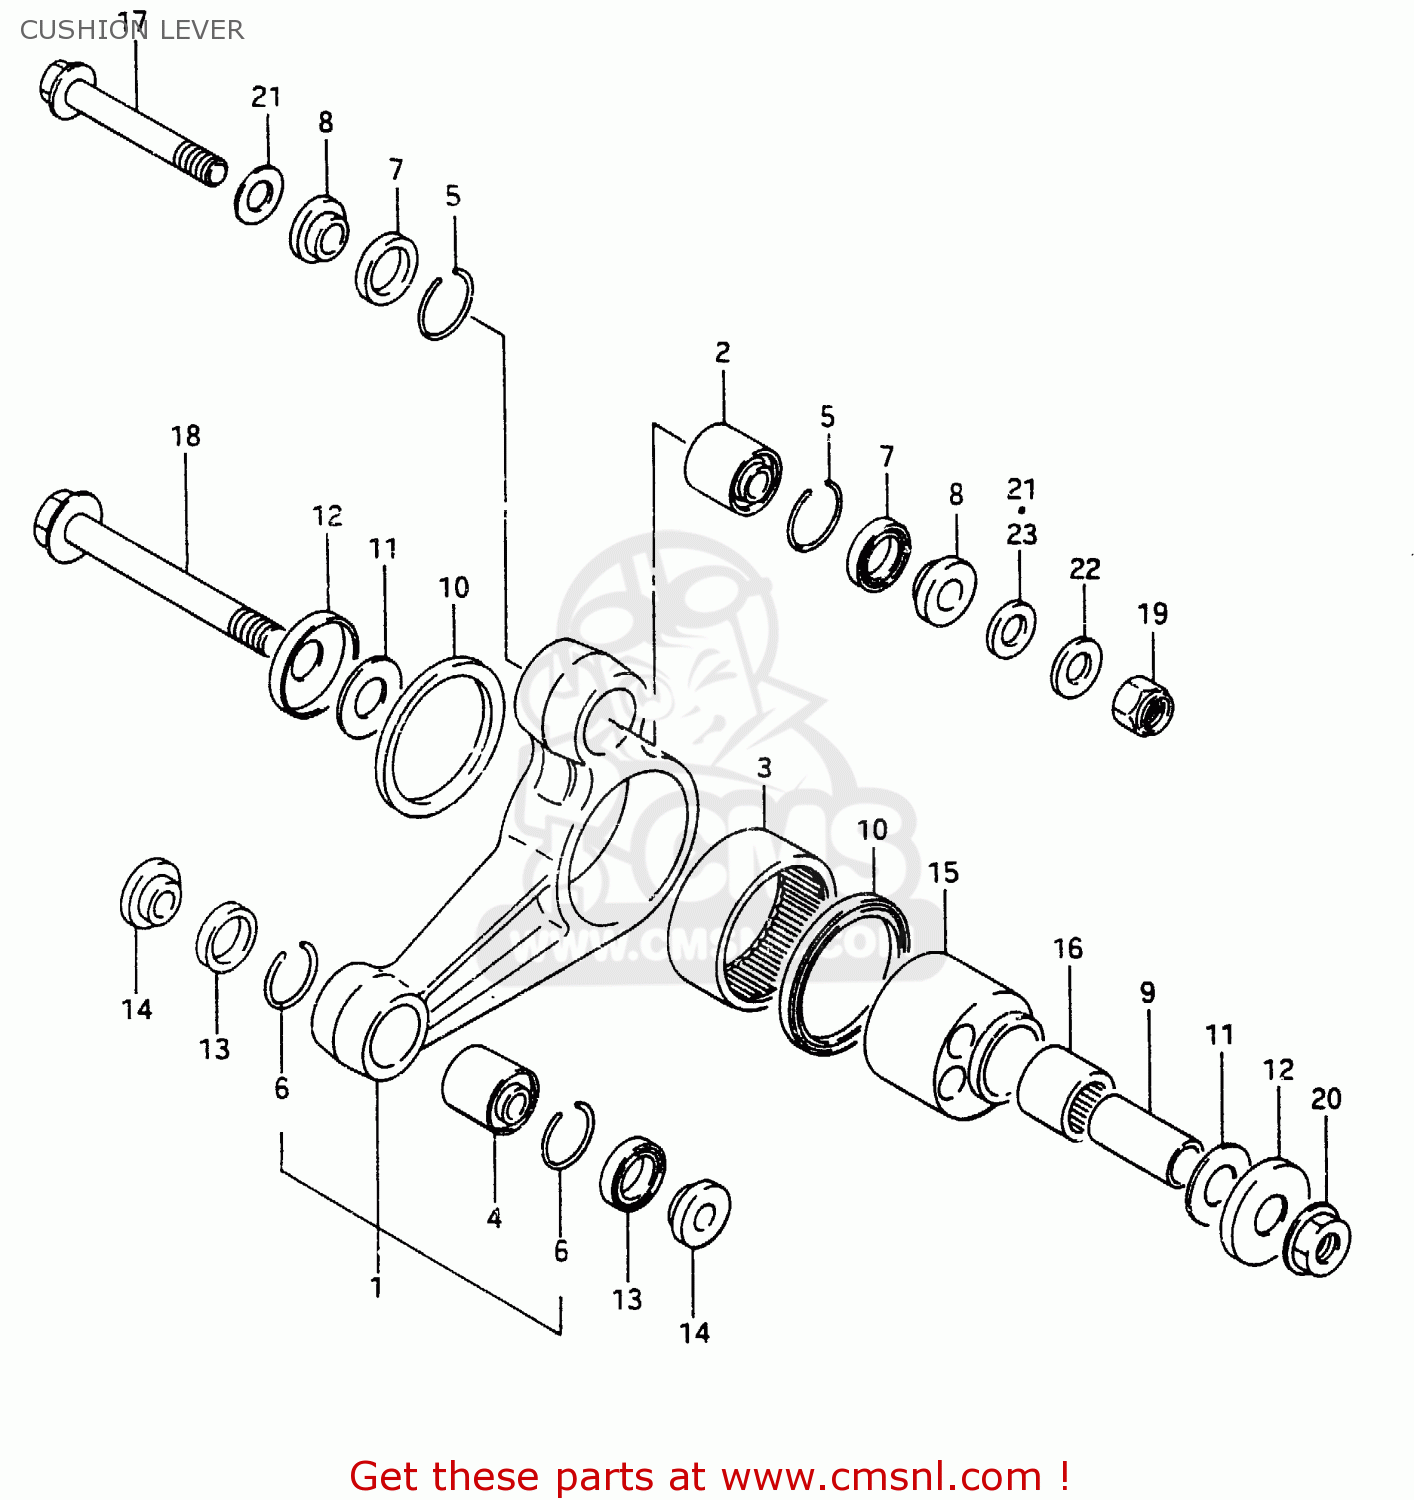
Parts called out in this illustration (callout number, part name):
1	LEVER SET, ECCENTRIC CUSHION
2	BEARING
3	BEARING(45X52X20)
4	BEARING(10X21X13)
5	RING,STOPPER
6	RING,BEARING STOPPER
7	DUST SEAL,RR CUSHION LEVER RR
8	SPACER
9	SPACER,ECCENTRIC LVR CTR
10	SEAL,ECCENTRIC LVR DUST CTR
11	WASHER
12	COVER,REAR SWING ARM DUST
13	SEAL,OIL(15X21X3)
14	SPACER,ECCENTRIC LVR RR
15	ECCENTRIC SPACER,REAR SUSPENSION
16	ROLLER BEARING (17X24X25)
17	BOLT(10X75)
18	BOLT(12X105)
19	NUT
20	NUT 12MM
21	SHIM
22	LOCK WASHER
23	WASHER
